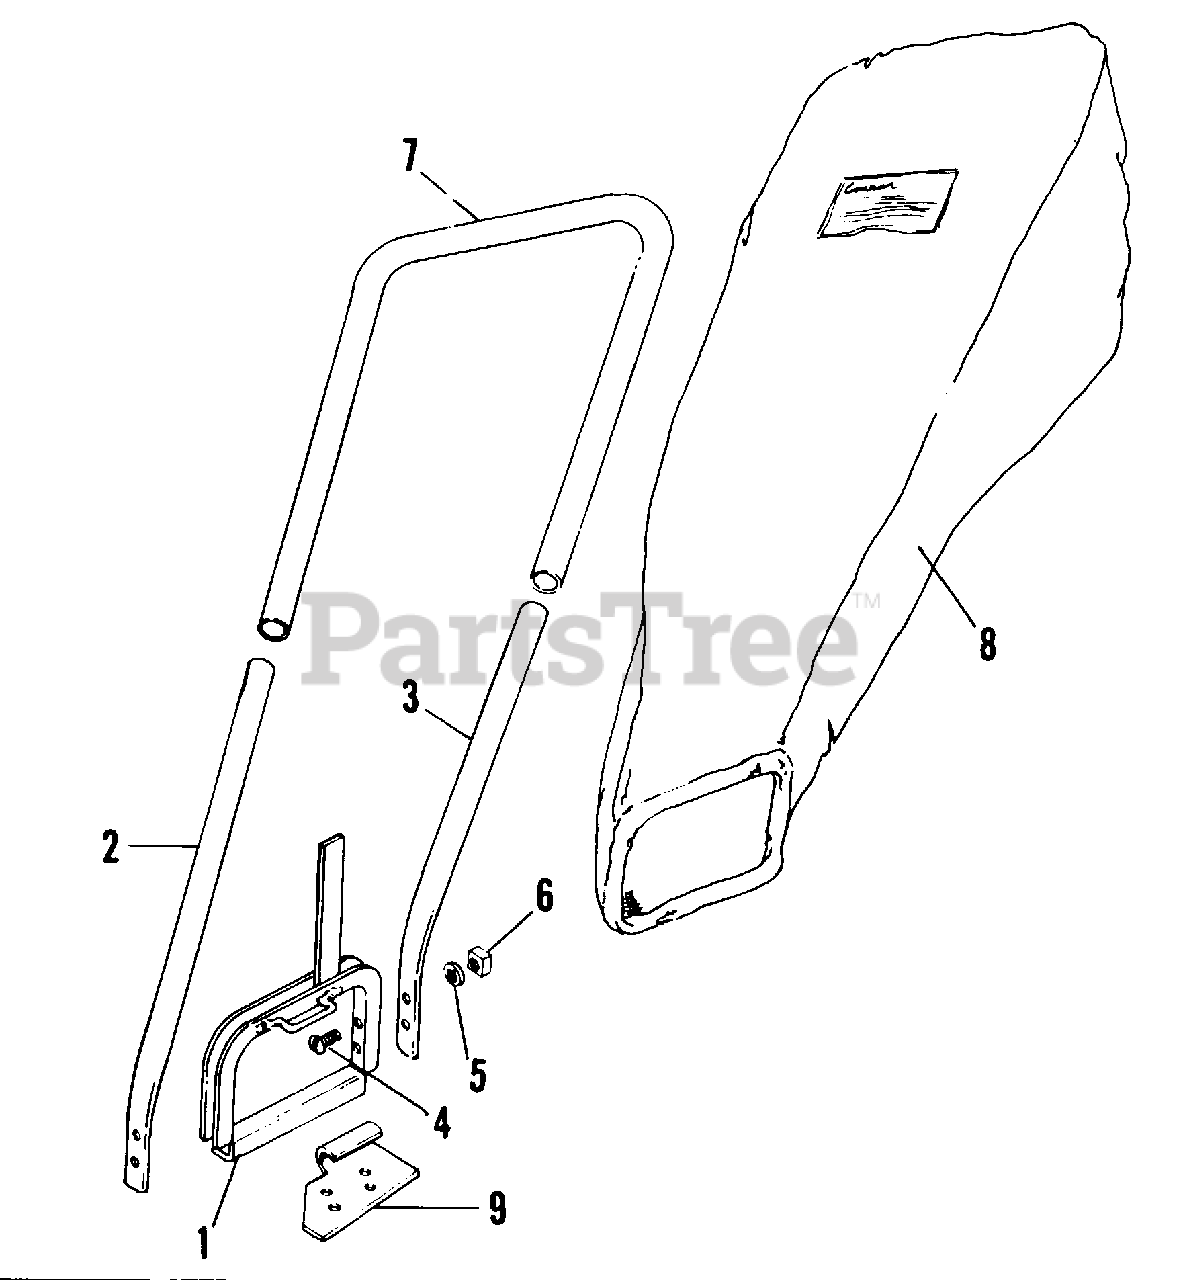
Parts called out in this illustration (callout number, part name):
1	FRAME, Bag Support
2	ROD, Bag (Long)
3	ROD, Bag (Short)
4	SCREW. Rd. Hd., 1/4-20
5	LOCKWASHER
6	NUT, Hex
7	TUBING, Bag
8	GRASS BAG
